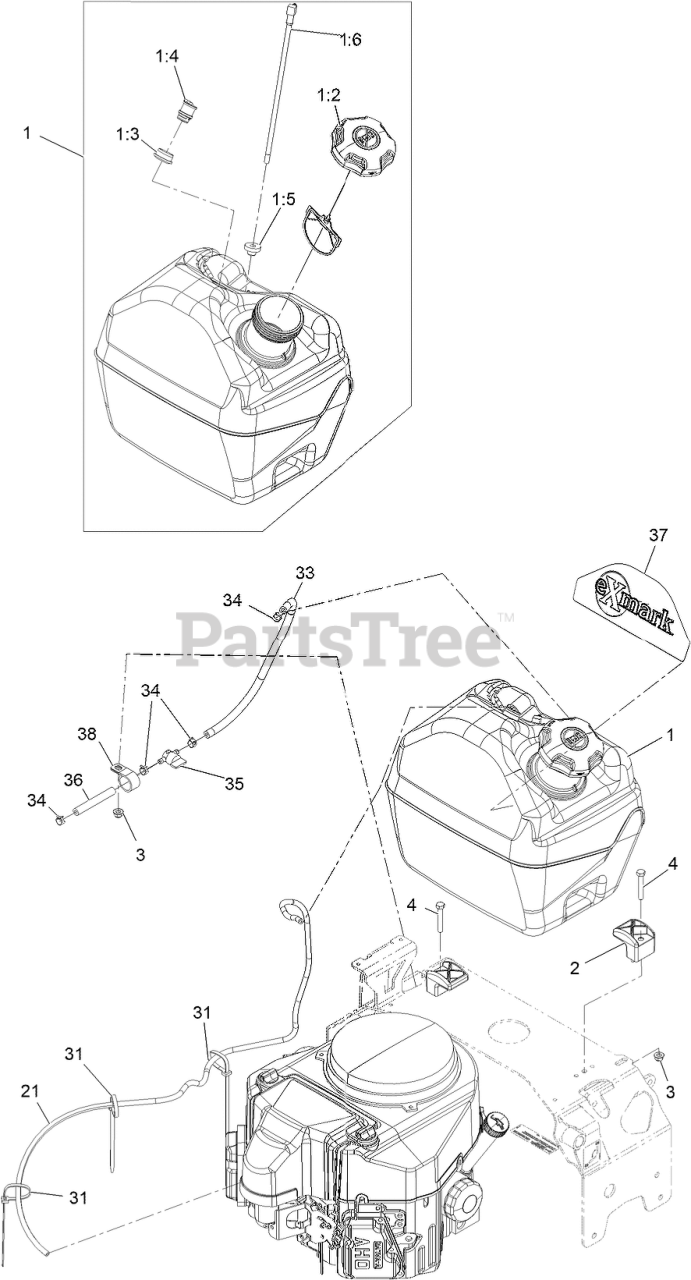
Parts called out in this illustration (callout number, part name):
1	Fuel Tank ASM, 5 Gal
1:2	CAP-FUEL, RATCHETING
1:3	GROMMET
1:4	VALVE-VENT, FUEL
1:5	BUSHING
1:6	FITTING, FUEL W/LINE AND SCREEN
3	NUT-HF, NI
4	SCREW-HH
21	HOSE-VENT
31	TIE-CABLE
33	HOSE-FUEL
34	CLAMP-HOSE
35	VALVE-FUEL
36	HOSE-FUEL
37	Artwork-Exmark Logo Fuel Tank
38	CLIP-LOOM
